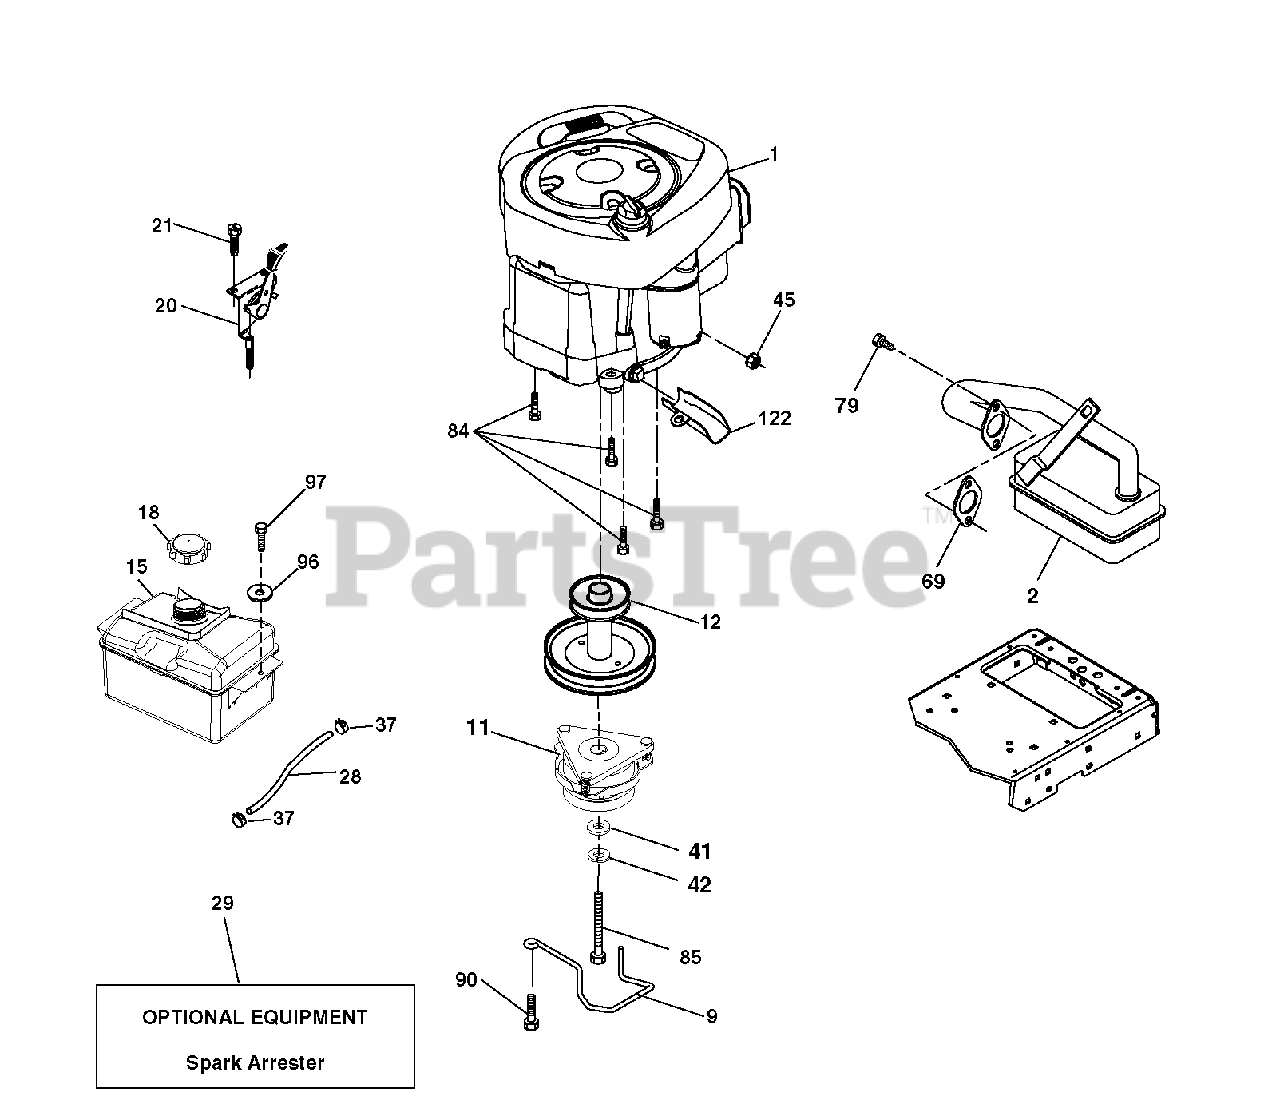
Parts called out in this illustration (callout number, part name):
9	KEEPER.BELT.ENGINE.3.25
11	CLUTCH
12	PULLEY.ASM.ENG.OGURA.3
15	TANK FUEL FRT 1.5 GAL
18	CAP.FUEL.2.25"VENTED"
20	CONTROL.TH/CK.C.
21	SCREW.#10 X 0.750.BOS THREAD
28	LINE.FUEL.20
29	ARRESTER SPARK (OPTIONAL)
37	HOSE CLAMP
42	LOCKWASHER
45	NUT
69	REPL BY 532 27 22-93
79	SCREW.SOCKET HD.5/16-1
84	SCREW.3/8-16
85	BOLT HEX 7/16-20X4-1/4"
90	SCREW 3/8-16X1
97	SCREW HEXWSHR 1/4-20X3/4
122	EXTENSION DRAIN OIL
